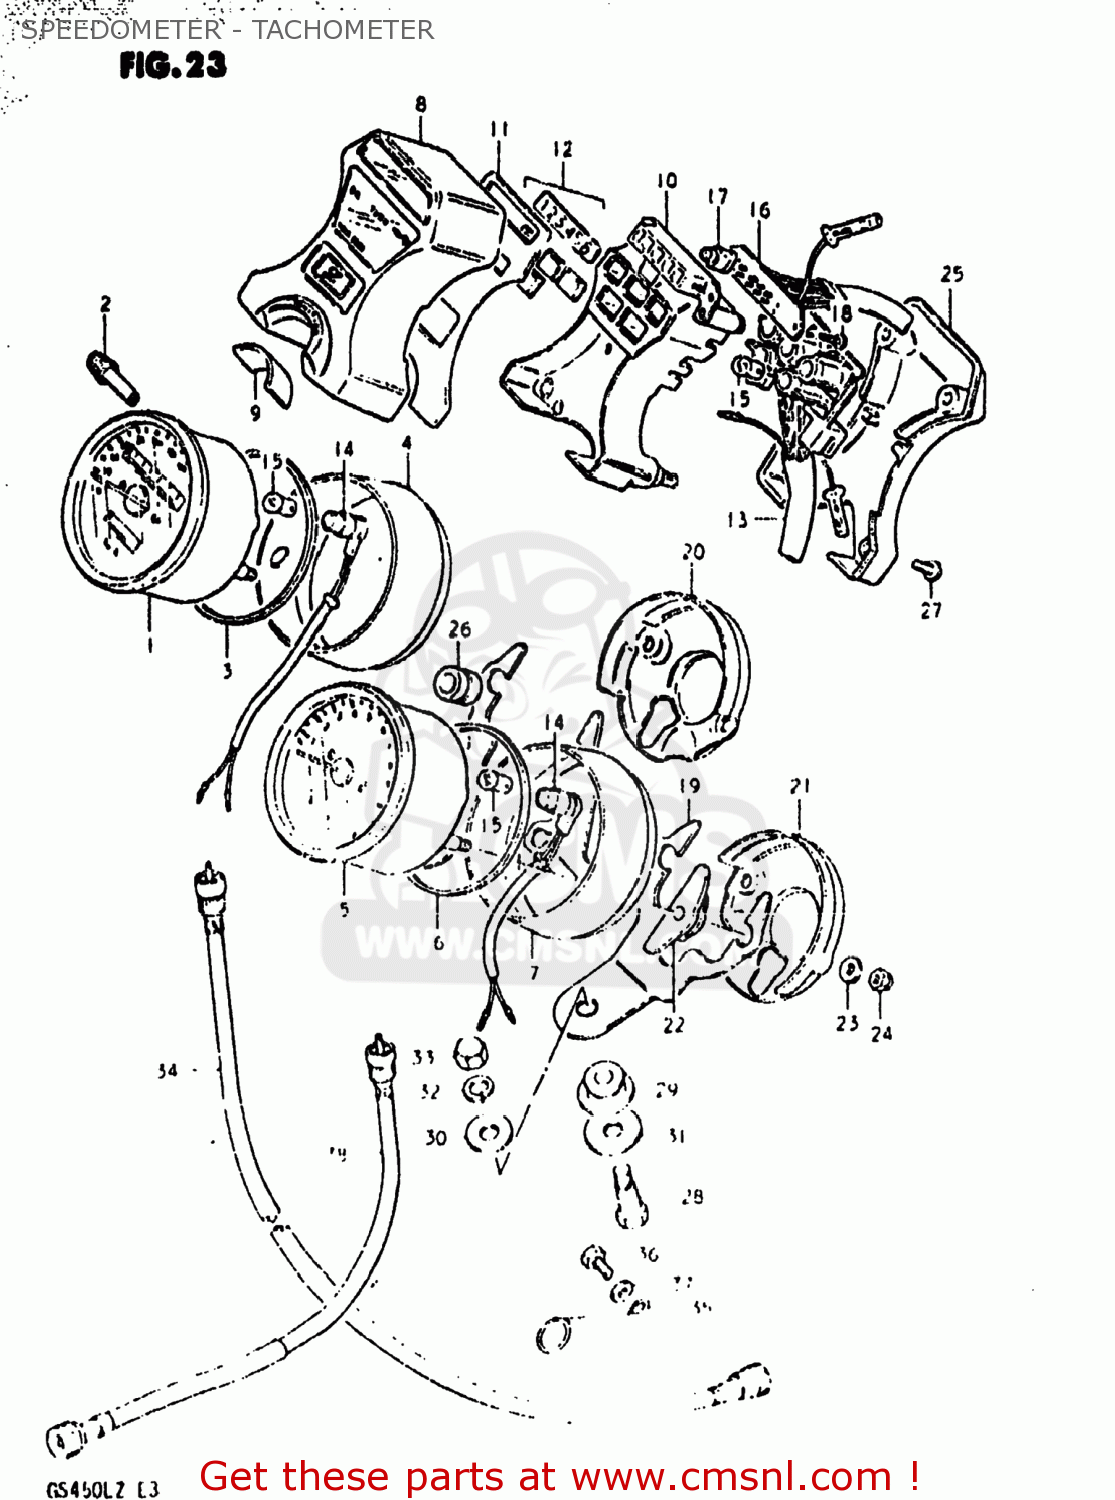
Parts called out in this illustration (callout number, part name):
1	METER,SPEEDOMETER
2	KNOB
3	CUSHION
4	COVER,SPEEDOMETER
5	TACHOMETER
6	CUSHION
7	COVER,TACHOMETER
8	CASE,PILOT BOX,OUTER
9	SEAL,IGNITION SWITCH
10	CASE,PILOT BOX,INNER
11	PLATE,PILOT BOX
12	LENS SET,PILOT
13	SOCKET
14	SOCKET,METER
15	BULB(12V3.4W,T10)
16	INDICATOR ASSEMBLY,GEAR POSITION
17	BULB(14V1.12W)
18	SCREW
19	BRACKET,COMBINATION METER
20	ORNAMENT,SPEEDOMETER
21	COVER,TACHOMETER
22	CUSHION,METER
23	WASHER
24	NUT
25	COVER,PILOT BOX,UNDER
26	CUSHION,PILOT BOX
27	SCREW,PILOT BOX
28	BOLT(8X31)
29	CUSHION,METER
30	WASHER(8.5X23X1.2)
31	WASHER
32	LOCK WASHER
33	NUT
34	CABLE ASSEMBLY,SPEEDOMETER
35	GUIDE,SPEEDOMETER CABLE
36	BOLT, UPPER
37	WASHER
38	CABLE ASSEMBLY,TACHOMETER
